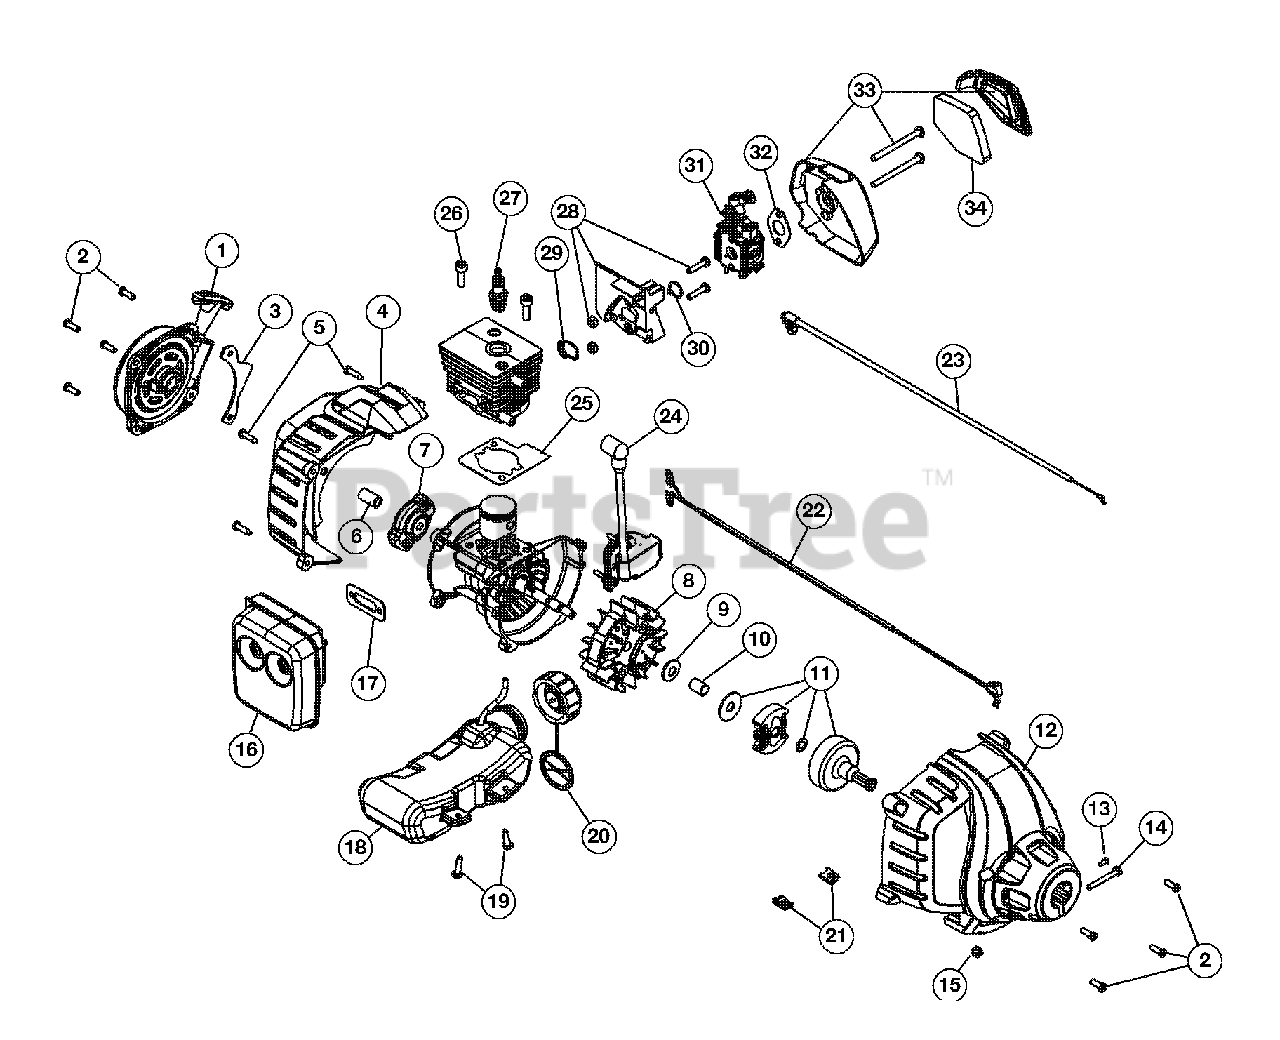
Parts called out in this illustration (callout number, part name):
1	Rear Cover Assembly
2	Starter Screw
3	Starter Assembly
4	Rear Engine Cover
5	Cover Screw
7	Pawl Assembly
8	Flywheel Assembly
11	Clutch Assembly
12	Clutch Cover Assembly
13	Anti Rotation Screw
14	Clamp Screw
15	Clamp Nut
16	Muffler Assembly
17	Muffler Gasket
18	Fuel Tank Assembly
21	U-Shaped Nut
22	Lead Wires
23	Throttle Cable
24	Module Assembly
25	Cylinder Gasket
26	Cylinder Bolt
27	Spark Plug
28	Insulator Assembly
29	Insulator O-Ring
30	Carburetor O-Ring
31	Carburetor
32	Carburetor Gasket
33	Aircleaner Assembly
34	Aircleaner Filter
